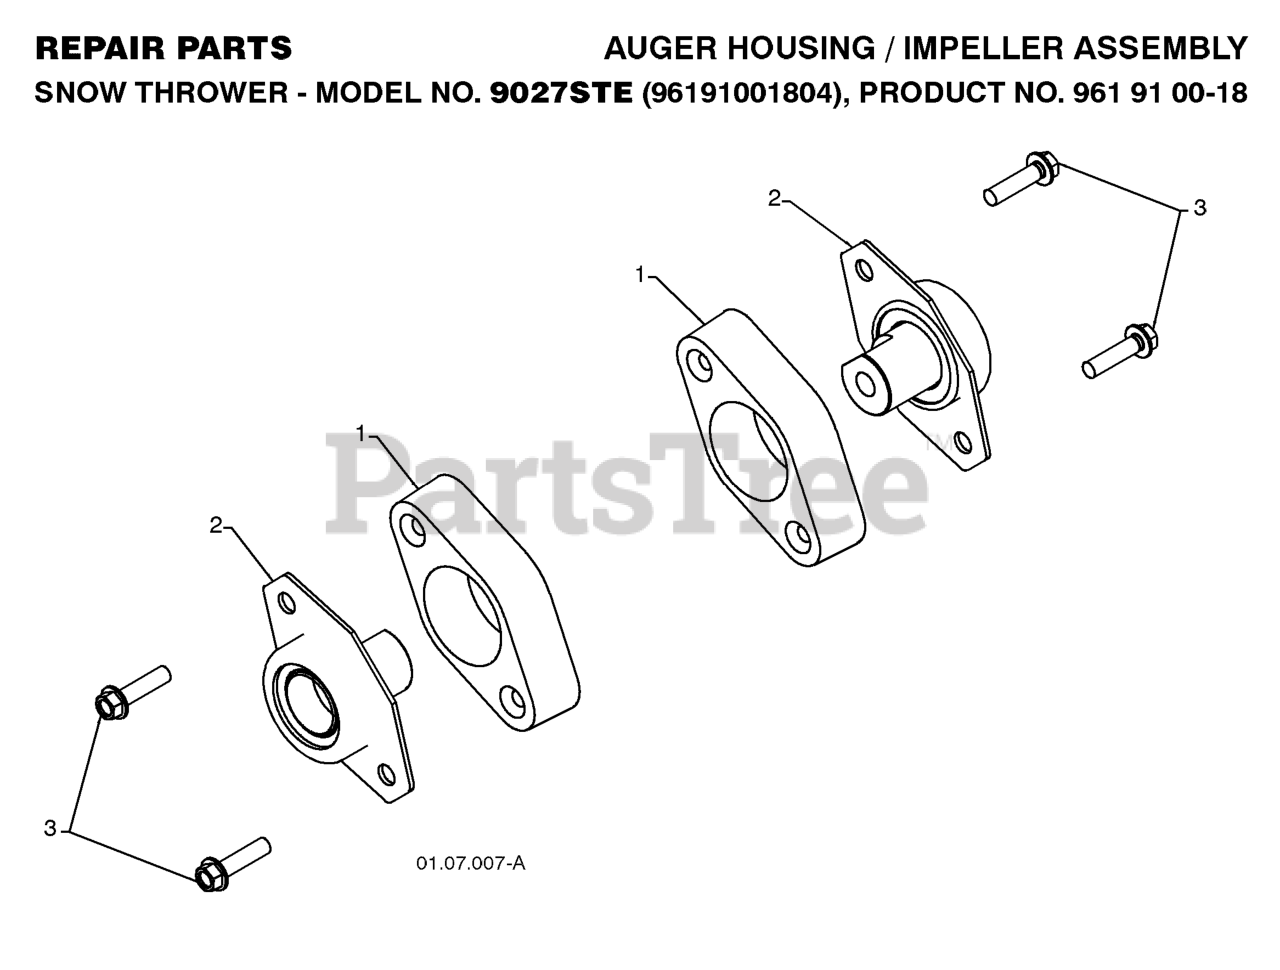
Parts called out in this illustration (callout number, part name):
1	BEARING RETAINER, PLASTIC
2	BEARING.BALL.AUGER
3	SCREW, HEX HD 5/16X1
